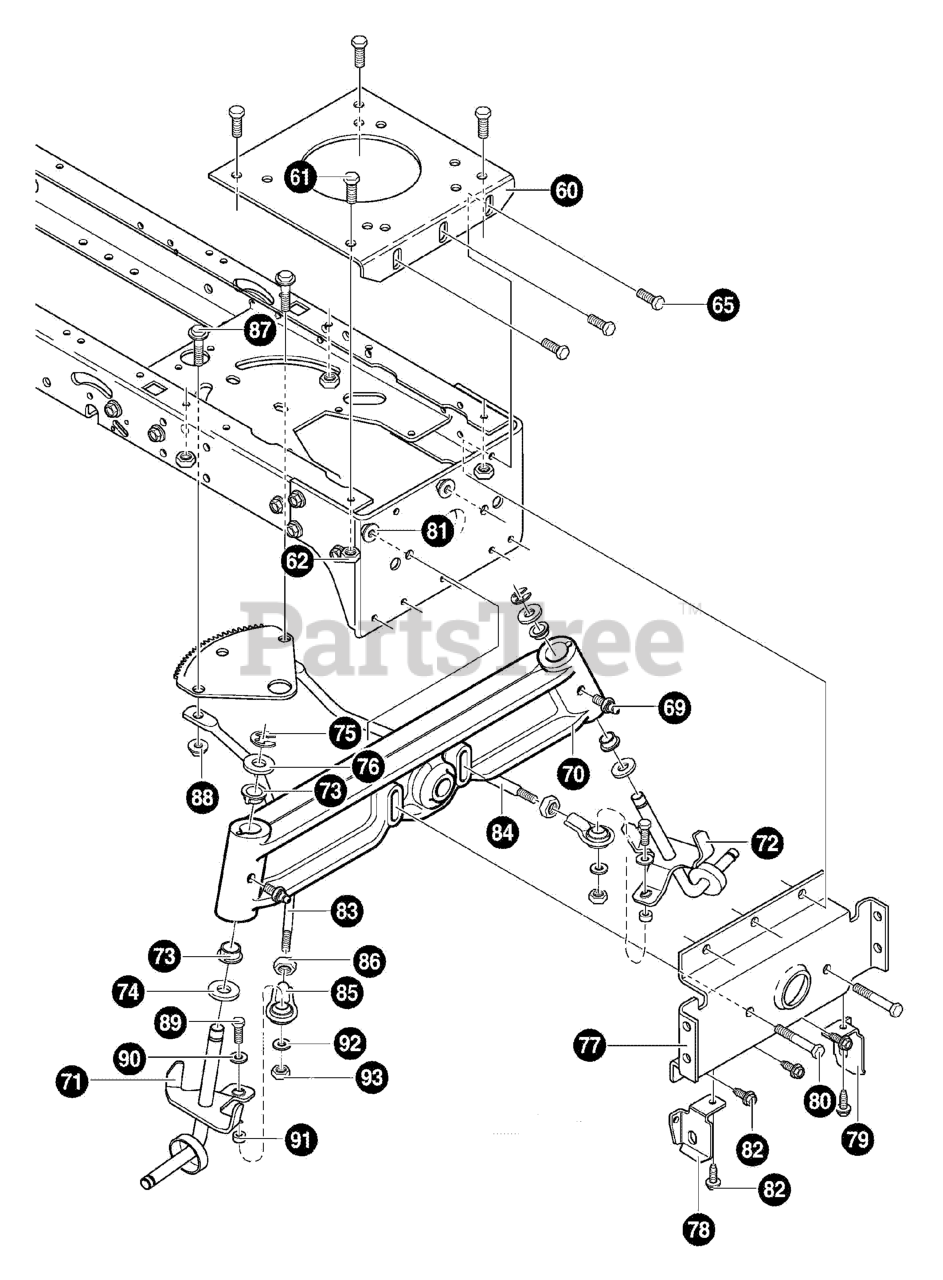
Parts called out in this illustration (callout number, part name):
60	PLATE, ENGINE
62	NUT
69	ZERK, GREASE FITTING
70	AXLE, FRONT
71	SPINDLE, RIGHT
72	SPINDLE, LEFT
73	BEARING, SPINDLE
77	HANGER, AXLE
78	HANGER, RIGHT DECK
79	HANGER, LEFT DECK
81	NUT
83	ROD, ADJUSTER
84	ROD, ADJUSTER
85	ROD END, TIE
88	NUT
90	WASHER
93	NUT
